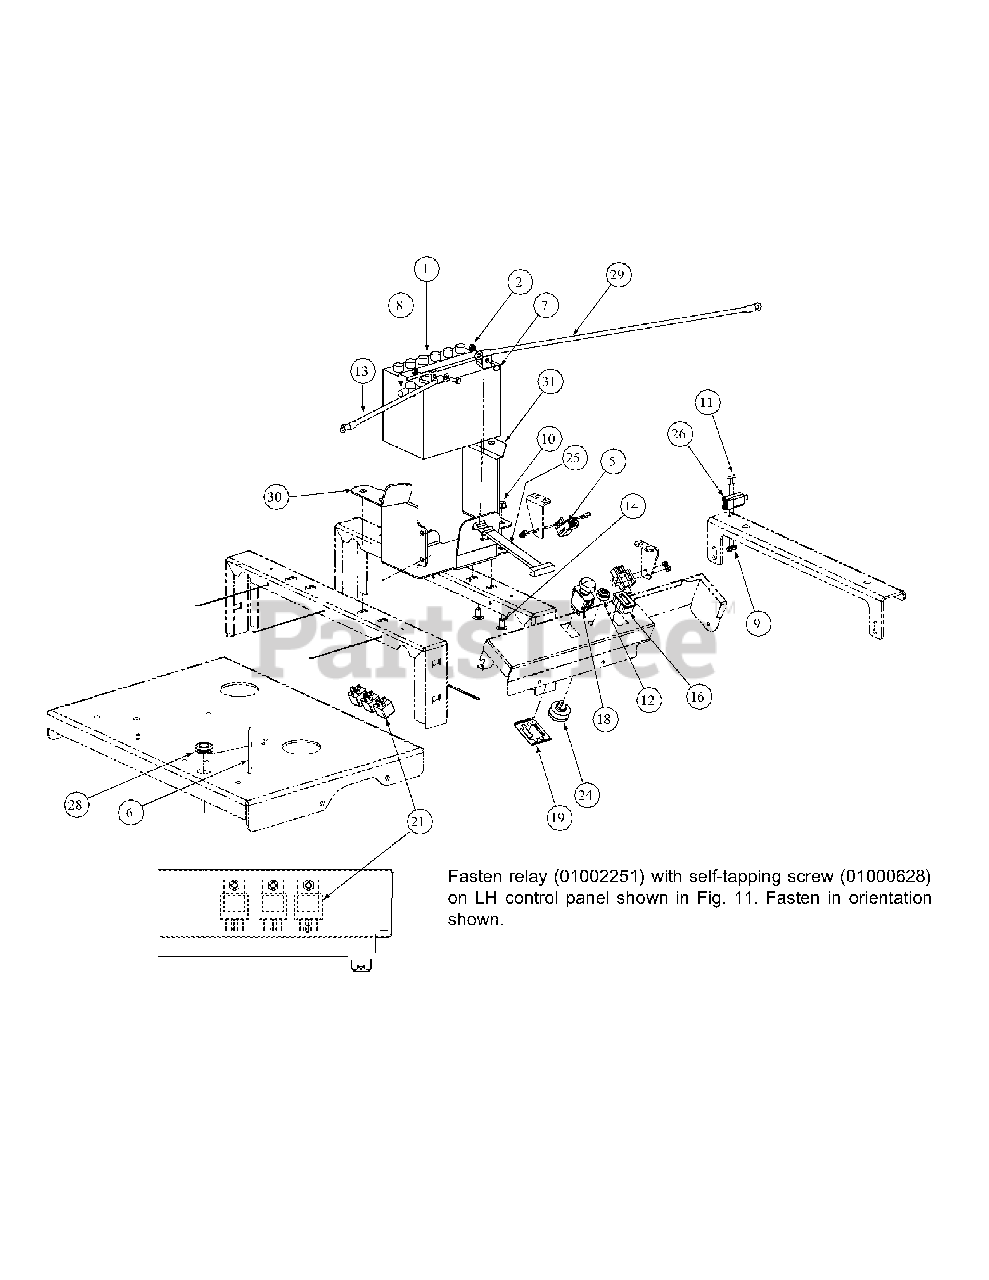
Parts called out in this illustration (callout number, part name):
1	Battery, 12V 225CCA 30 Min
2	Lock Nut, 1/4-20
5	Switch, Safety
6	Tie, Cable, 3/16 x .05 x 7.4"
7	Screw, Hex, Cap, 1/4-20 x .75
8	Boot, 1" OD Rubber Battery-PST, Red
9	Lock Nut, Nylon Insert
10	Nut, Hex, Flange Lock, 3/8-16
11	Screw, Phillips Head, Machine, 10-32 x 5/8
12	Nut, W/Cap, 5/8-32 Ignition
13	Cable, Battery, Red, 36"
14	Carriage Bolt, 3/8-16 x .75 LG.
16	Meter, Hour (Honda)
16	Meter, Hour (Kohler)
18	Switch, Electric, PTO
19	Bracket, PTO Switch Retainer
21	Relay, 12V 40A
24	Switch, Ignition, 6 Pin
24	Key, Ignition
25	Strap, Battery
26	Switch, Plunger
28	Grommet, .75 ID
29	Cable, Battery Red, 28"
30	Mount Bracket, Battery
31	Mount Bracket, Battery
31	Mount Bracket, Battery, One Piece
